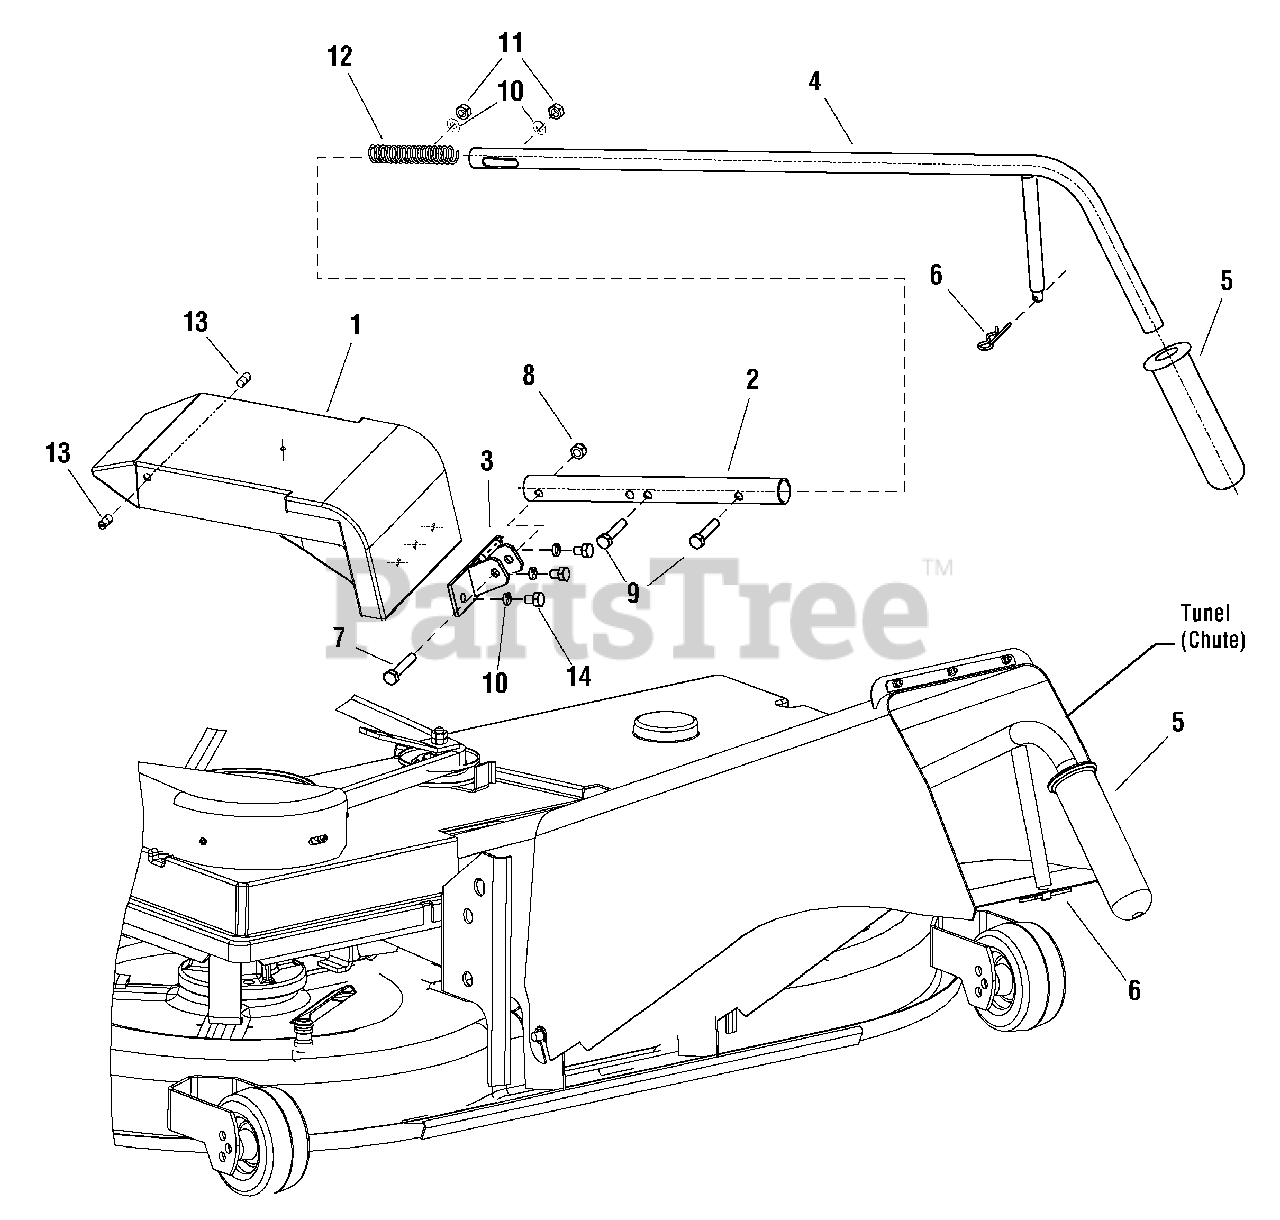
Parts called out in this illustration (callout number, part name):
1	MOWING FLANGE, 9-8547-386
4	FULL TUBE
5	HANDLE, 02/20-110-RED
6	SPLIT PIN, 0-9245-24
7	SCREW, M8 x 45 CSN021103.55
8	NUT, M8 CSN021492.55
9	SCREW, M8 x 35 CSN021103.55
10	WASHER, 8 CSN021740.15
11	NUT, M8 CSN021401.55
12	SPRING, TLZ200.180.0950
13	CASING, 0-9311-816
14	SCREW, M8 x 12 CSN021103.25
